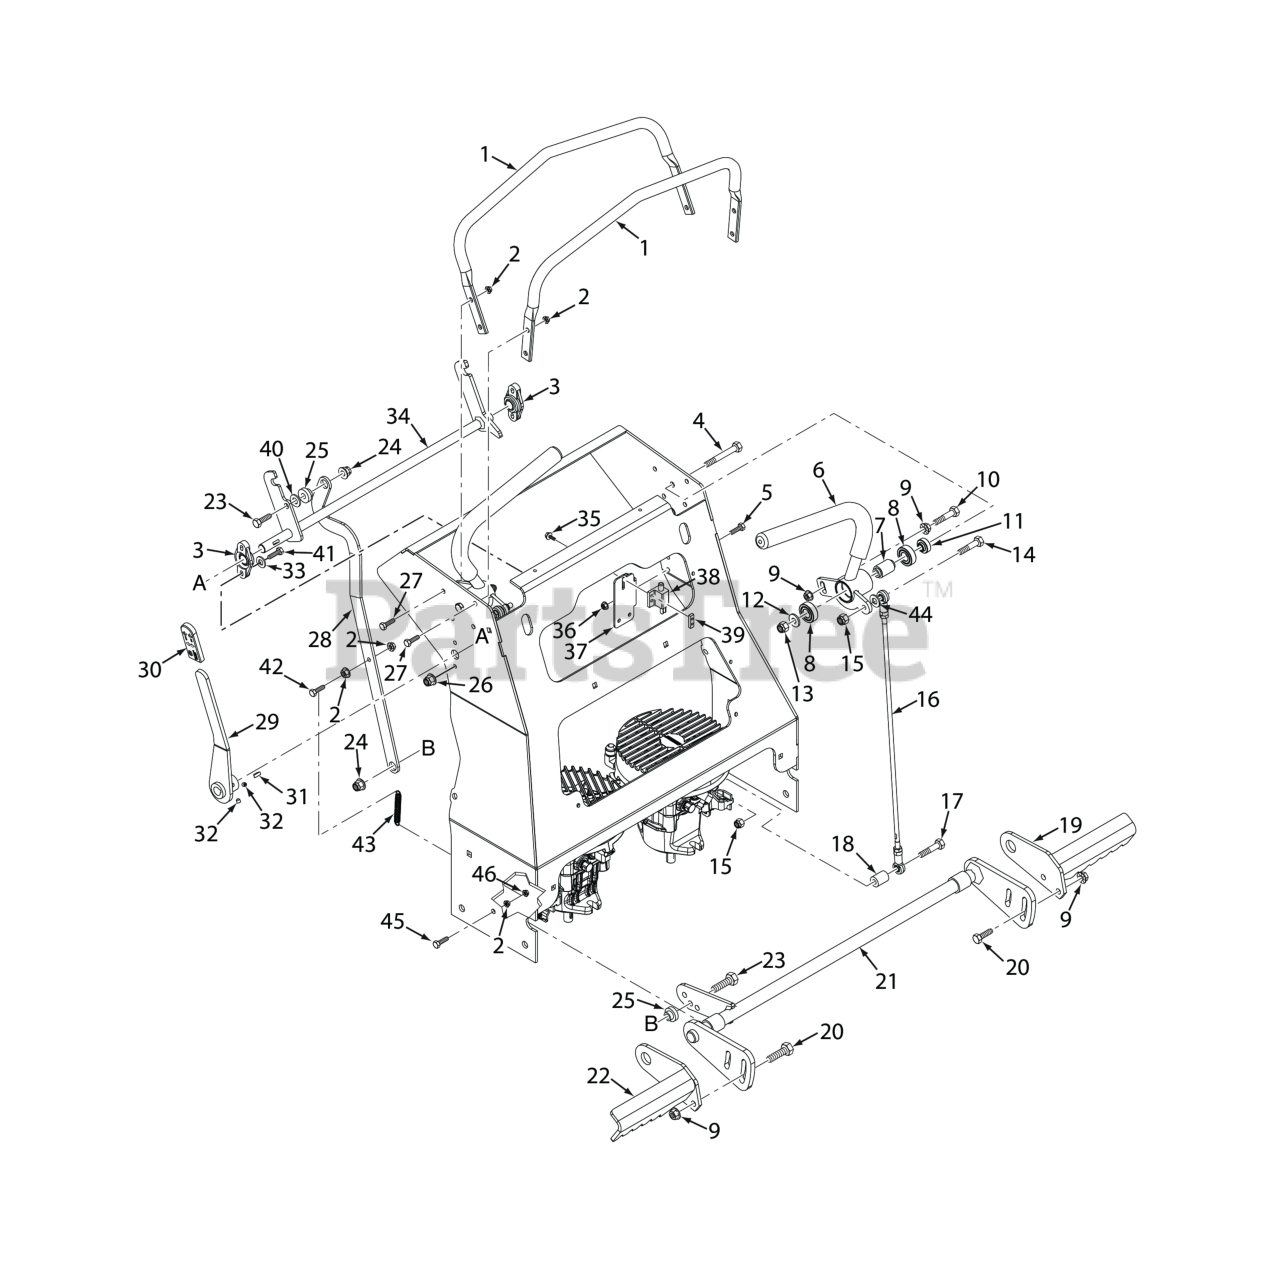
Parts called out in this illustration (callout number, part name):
1	Reference Bar
2	Nut, Serrated Flange 5/16-18 (Right Front Engine Mounting, Briggs and Kohler Only)
3	Bearing
4	Capscrew, Hex Head 3/8-16 x 3.25"
5	BOLT, HEX HEAD, 1/4-20 X 3/4 GR.5
6	Handlebar Assy., LH
7	Spacer, Bearing
8	BEARINGS, BALL, NEUTRAL RETURN
9	NUT, 3/8-16 SERRATED FLANGE HEX HEAD
10	Capscrew, Hex Head 3/8-16 x 2.0"
11	Spacer, Controls
12	Flatwasher, 3/8 (.391 x .938 x .105 HD) Grade 8
13	HEX NUT, ELASTIC STOP LOCK, 3/8-16
14	Bolt, 5/16 - 18 x 1 - 1/4" Hex Head
15	HEX NUT, ELASTIC STOP LOCK, 5/16-18
16	Linkage Assy., Steering
17	Bolt, Hex Head 5/16-18 x 2-1/2" (x3) (35BV & 37BV-EFI)
19	Brake Paddle Weldment, RH
20	Carriage Bolt, 3/8-16 x 1.0"
21	Bellcrank Weldment, Brake
22	BRAKE PADDLE WLMT, LH
23	Bolt, Hex Head 3/8-16 x 1-1/4", Kawasaki FX / FT & FT-EFI
24	Nut, Flange Elastic Stop Nut, 3/8-16
25	BUSHING, BRONZE - .376 ID X .627 OD
26	Nut, Flanged Elastic Stop 1/4-20
27	BOLT, SERRATED FLANGE HEX HEAD 5/16-18 X 3/4"
28	Link, Brake Engage
29	Brake Lever Assy. - SVRII (Incl. #30)
30	Grip, Parking Brake
31	KEY, 3/16 X 3/16 X 1-1/2
32	Set Screw 1/4-20 x 1/4"
33	Flatwasher, 1/4 (.281 x .625 x .065)
34	Lock Weldment, Neutral
35	Screw, Hex-Slotted Washer Head #10 32 x 3/4"
36	NUT, 1/4-20 SERRATED FLANGE HEX HEAD
37	Bracket, Neutral Switch
38	Switch, Interlock, Park Brake Normally Open
39	Plate, Threaded
41	Capscrew, Hex Head 1/4-20 x 1"
42	Bolt, Hex Head 5/16-18 x 1-1/2" (Right Front Engine Mounting, Briggs and Kohler Only)
43	Spring, Deck Lift
44	Flatwasher, 5/16-.344 x .688 x .065 (48V / 52V)
45	Bolt, Hex Head 5/16-18 x 1-1/2" (Right Front Engine Mounting, Briggs and Kohler Only)
46	Nut, Serrated Flange 5/16-18 (Right Front Engine Mounting, Briggs and Kohler Only)
